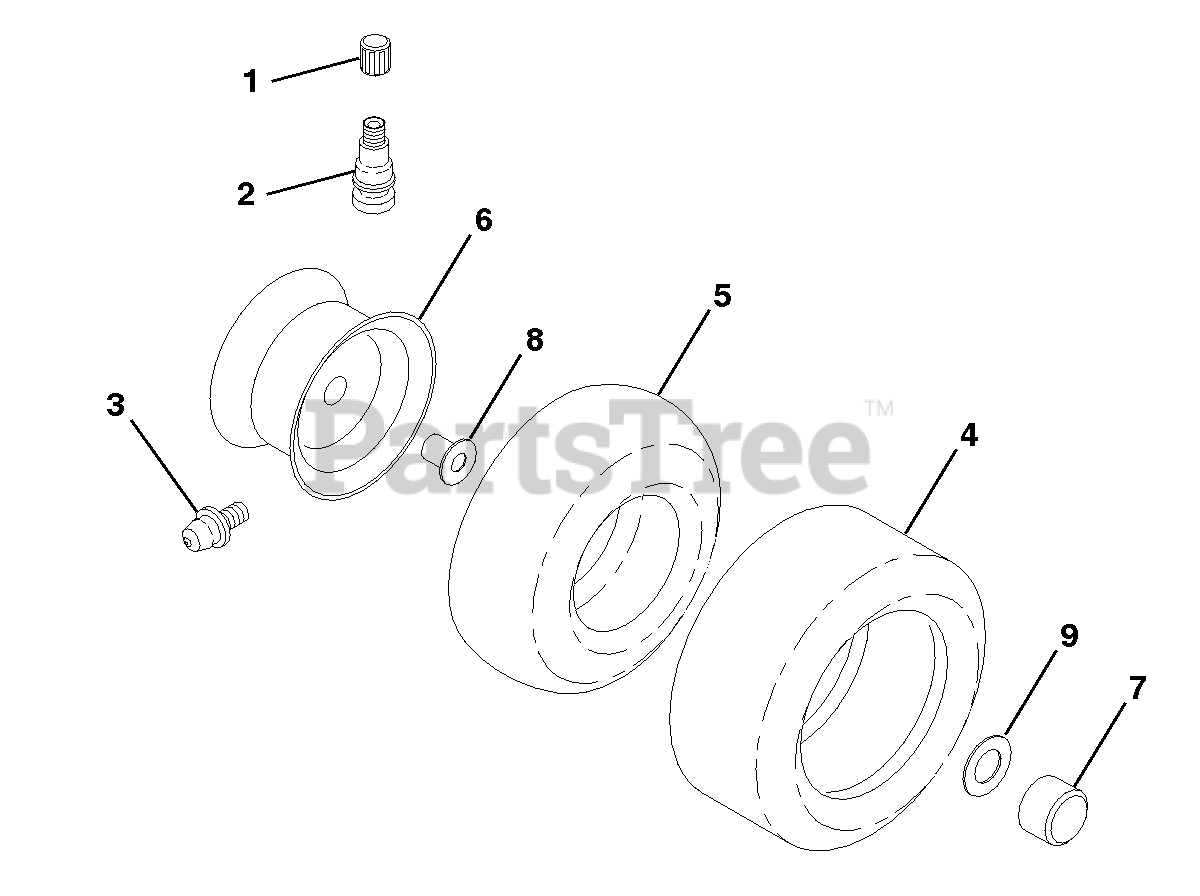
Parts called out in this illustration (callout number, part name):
1	Cap, Valve
2	Stem, Valve
3	Fitting, Grease
4	Tire, Front
4	Tire, Rear
5	Tube, Front
5	Tube, Rear
6	Rim, Front
8	Bearing Flange
9	Washer 25/32 x 1-5/8 x 16 Ga.
